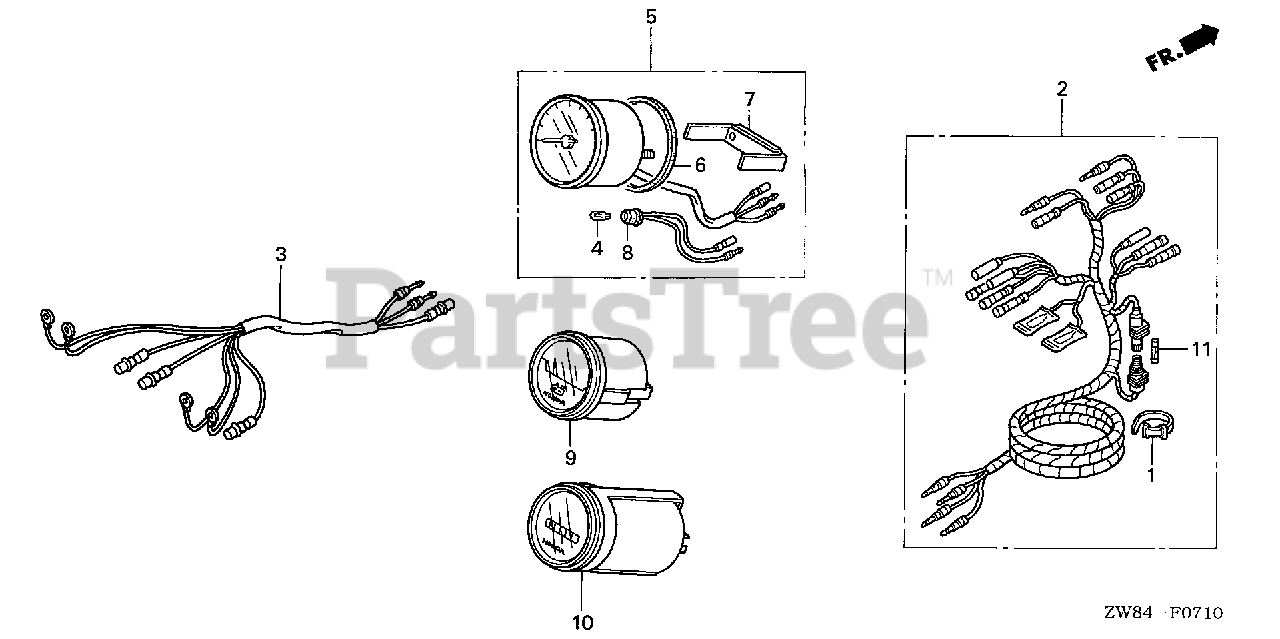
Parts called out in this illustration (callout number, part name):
1	BAND B1, CABLE
2	HARNESS ASSY., METER (A)
3	HARNESS ASSY., METER (B)
4	BULB, WEDGE BASE (12V1.7W)
5	TACHOMETER ASSY.
9	METER ASSY., VOLT
10	METER ASSY., HOUR L.C.D.
11	FUSE A (10A)
